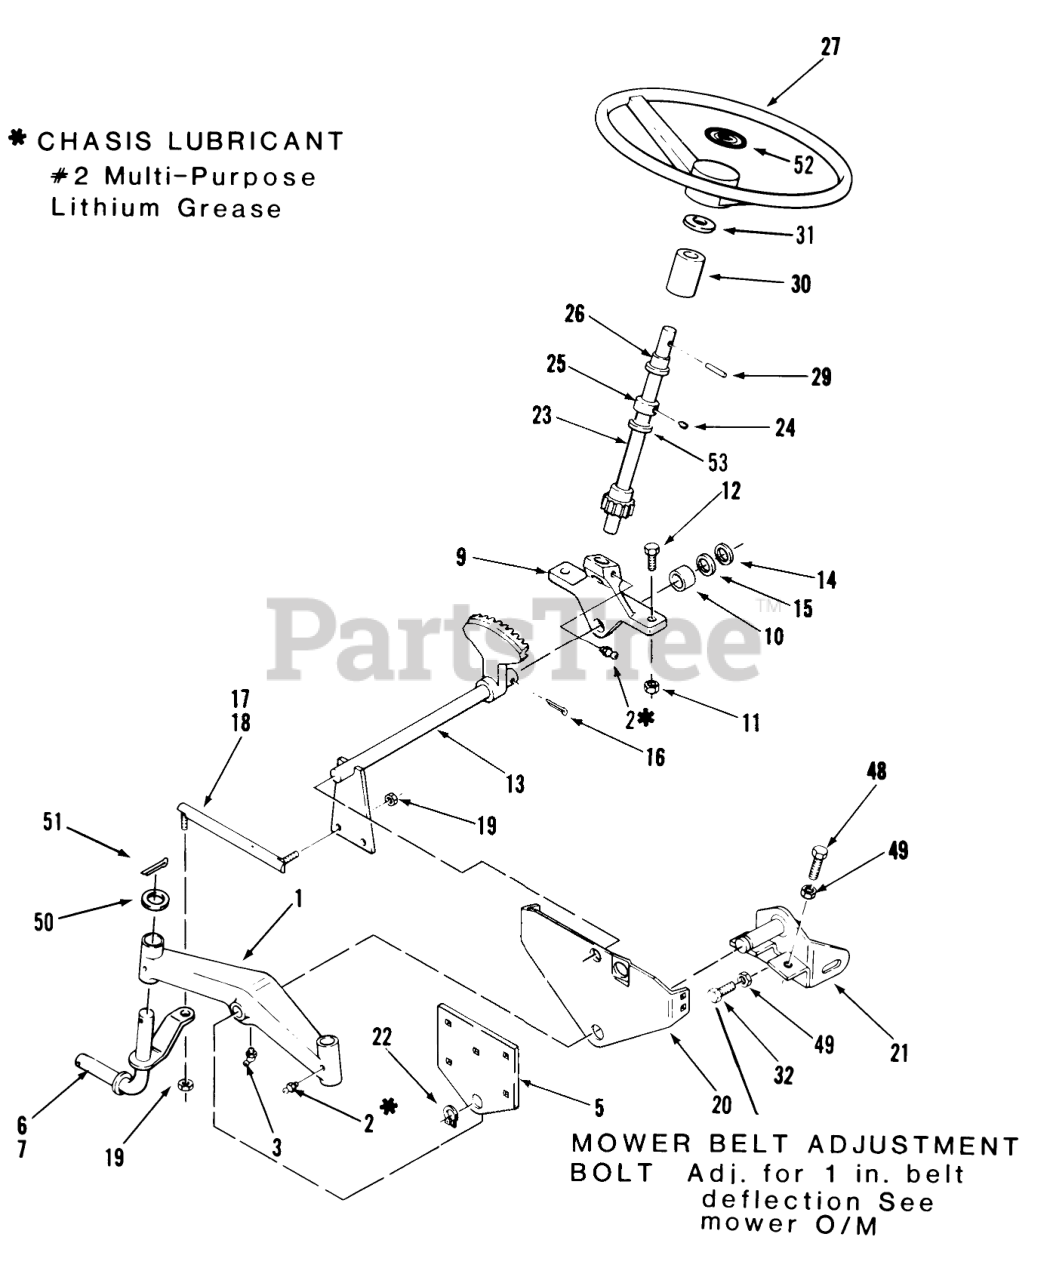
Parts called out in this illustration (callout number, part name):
1	AXLE-FRONT R
2	Zerk
3	FITTING-GREASE
5	PLATE-FRONT AXLE R
6	Front Spindle Assy RH
7	Front Spindle Assy LH
9	Support
10	BEARING-BRONZE
11	Nut
12	BOLT
13	ASSY STEER SHAFT LOW
14	WASHER-SHIM
15	WASHER
16	PIN-4
17	25LL JOINT ASSY R R
18	BALL JOINT ASSY L R
19	NUT-6
20	SUPPORT AXLE R
21	ASSY-FRONT HANGER R
22	Snap Ring
23	ASSY-STEER SHFT U R
24	SCREW-SET
25	Collar
26	BEARING-FLANGED
27	STEERING WH 13" PLAS
29	Pin-Roll
30	Collar 208-3 Only
31	WASHER-FLAT
32	SCREW-HH
48	Bolt
49	Nut
50	WASHER
51	COTTER PIN-4
52	STEERING WHEEL INSE
53	RING-RETAINING
